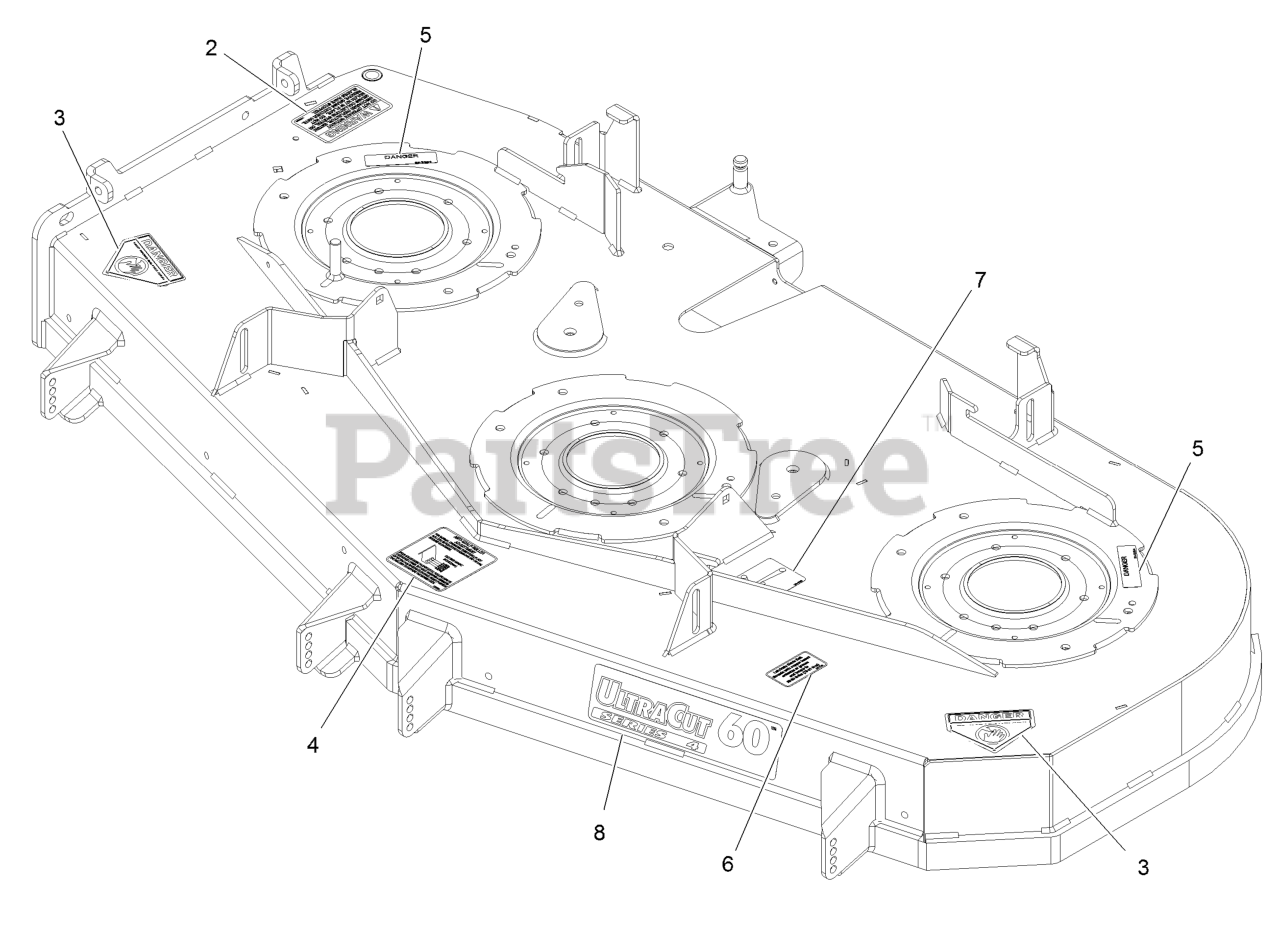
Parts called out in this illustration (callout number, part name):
2	DECAL-WARNING, DISCHARGE
3	DECAL-DANGER
4	DECAL,ANTISCALP
5	DECAL-COVER, MISSING
6	DECAL,BOLT TORQUE
7	DECAL-ROUTING, BELT
8	DECAL,ULTRACUT 60 SERIES
